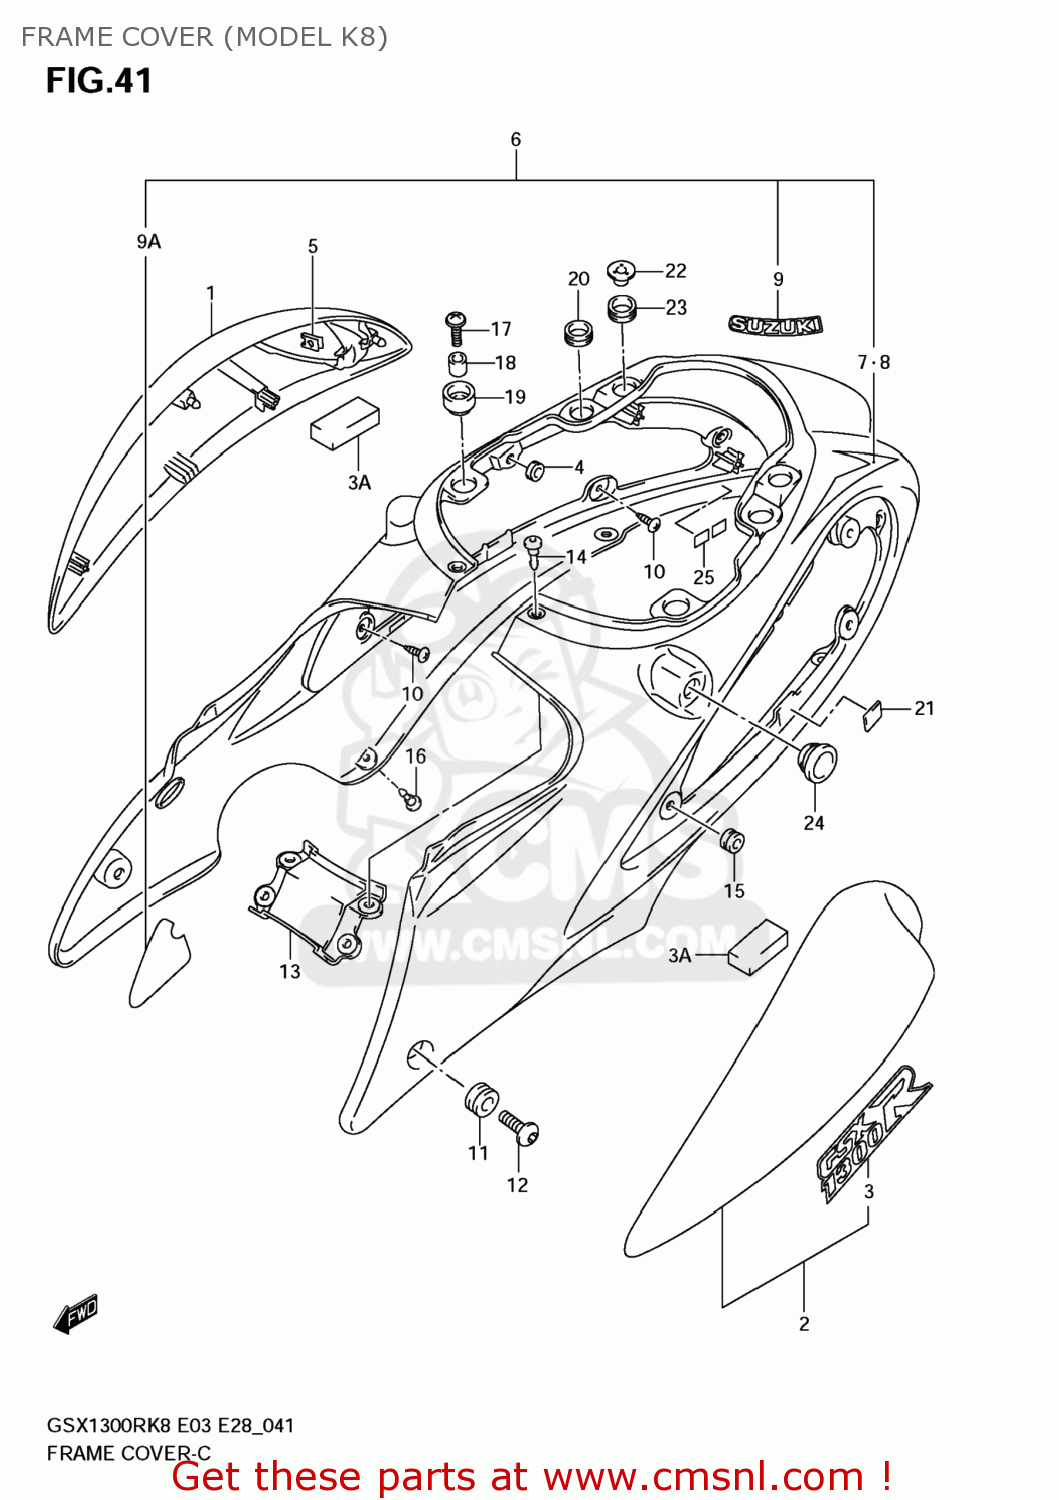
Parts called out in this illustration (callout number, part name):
1	COVER COMP,FRA
2	COVER COMP,FRA
3	EMBLEM,FRAME COVER
3A	CUSHION,FRAME COVER
4	CUSHION
5	NUT
6	COVER,FRAME CTR
7	TAPE,COVER CTR,R
8	TAPE,COVER CTR,L
9	EMBLEM,SUZUKI
9A	TAPE,CTR
10	SCREW GSX1300R
11	CUSHION
12	SCREW(6X20)
13	LID,FRAME COVER CTR
14	CLIP(BLACK)
15	CUSHION
16	CLIP
17	SCREW(6X20)
18	SPACER(6.5X10X11)
19	CUSHION,SEAT TAIL COVER CTR
20	CUSHION,FRAME COVER UPR RR
21	PROTECTOR(170X95X3.0)
22	WASHER,FRAME COVER
23	CUSHION,FRAME COVER UPR RR RR
24	CUSHION,FRAME COVER CTR
25	CUSHION,SEAT TAIL COVER LWR RR
